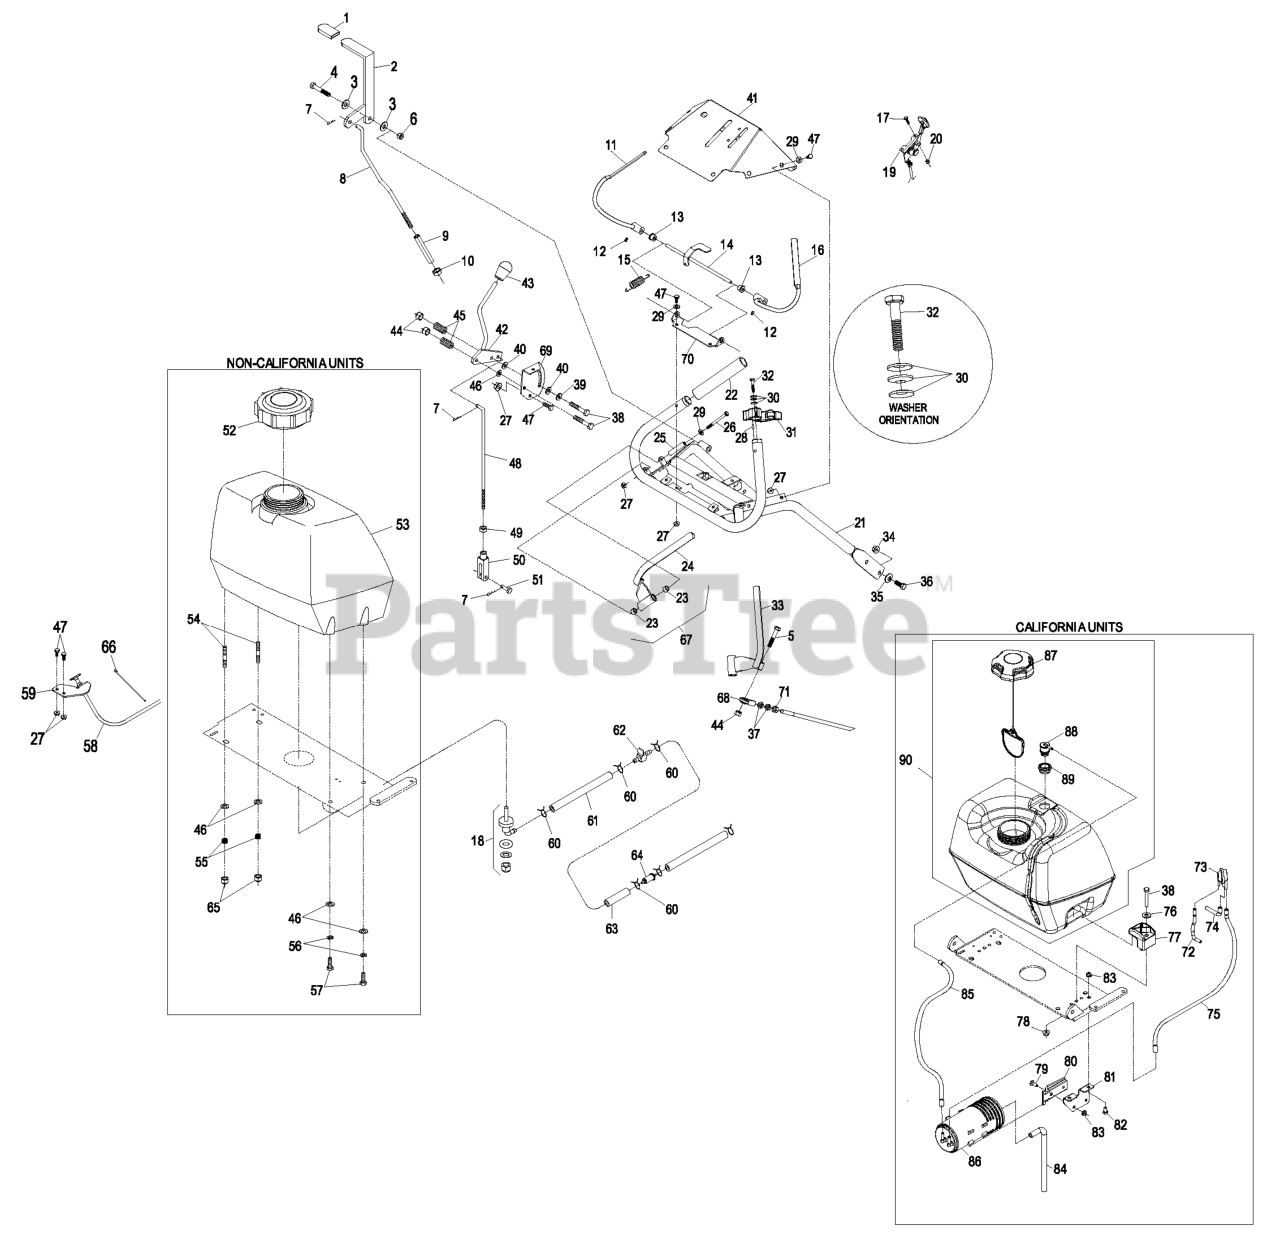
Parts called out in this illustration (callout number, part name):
1	GRIP-LEVER
3	WASHER-FLAT
4	SCREW-HH
5	SCREW-HH
6	NUT-LOCK, NI
7	PIN-COTTER
8	LINK,BLADE ENGAGE (PLTD)
9	TURNBUCKLE
10	NUT-HEX
12	SCREW-SET
13	BUSHING-NYLON
14	WLD,OPC LEVER AXLE
15	SPRING-EXTENSION
17	BOLT-CARR
18	FITTING-FUEL, BULKHEAD
19	CONTROL, THROTTLE
20	NUT-LOCK, NI
21	WLD,UPPER ECS HANDLE
22	GRIP-BAR, HANDLE
23	BUSHING-SLEEVE
25	BUSHING-LEVER, DRIVE
26	SCREW-HH
27	NUT-HF
29	WASHER-FLAT
30	WASHER-SPRING
31	ASM,LATCH RH THUMB
32	SCREW-HH
34	NUT-HHF, WHIZ
35	WASHER-BELLEVILLE
36	SCREW-HH
37	NUT-HJ
38	SCREW-HH
39	WASHER-FRICTION
40	WASHER-FRICTION
41	ASM,CONSOLE W/DECALS
43	KNOB, FE.LCKG. BLACK
44	NUT-LOCK, NI
45	SPRING-COMPRESSION
46	WASHER-PLAIN
47	SCREW-HH
48	ROD,SPEED CONTROL
49	NUT-JAM
50	YOKE-ADJUSTABLE
51	PIN-CLEVIS
52	CAP-FUEL, GAS
53	ASM,FUEL TANK W/B
54	STUD
55	SPRING-TANK, FUEL
56	WASHER-LOCK
57	SCREW-HH
58	CABLE-CHOKE
59	BRACKET-CABLE, CHOKE
61	HOSE-FUEL
62	VALVE-FUEL
63	HOSE-FUEL
64	Pn 41019-1055 Filter W/6" Fuel Line
65	NUT-LOCK, NI
66	TIE-CABLE
67	DRIVE LEVER-ASM, RH
68	JOINT-BALL, END
69	BRACKET,SHIFTER SLIDE (PL
70	BRACKET,OPC AXLE
71	NUT-HEX
72	HOSE-VENT, FORMED
73	VALVE-CONTROL, VACUUM
74	HOSE-VENT, FORMED
75	HOSE-VENT, FORMED
76	WASHER-FLAT
78	NUT-HF, NI
79	SCREW-HH
80	BRACKET-CANISTER, CARBON
81	BRACKET-CANISTER, CARBON
82	BOLT-CARR
84	HOSE-VENT, CANISTER
85	HOSE-VENT
86	CANISTER-CARBON, 800CC
